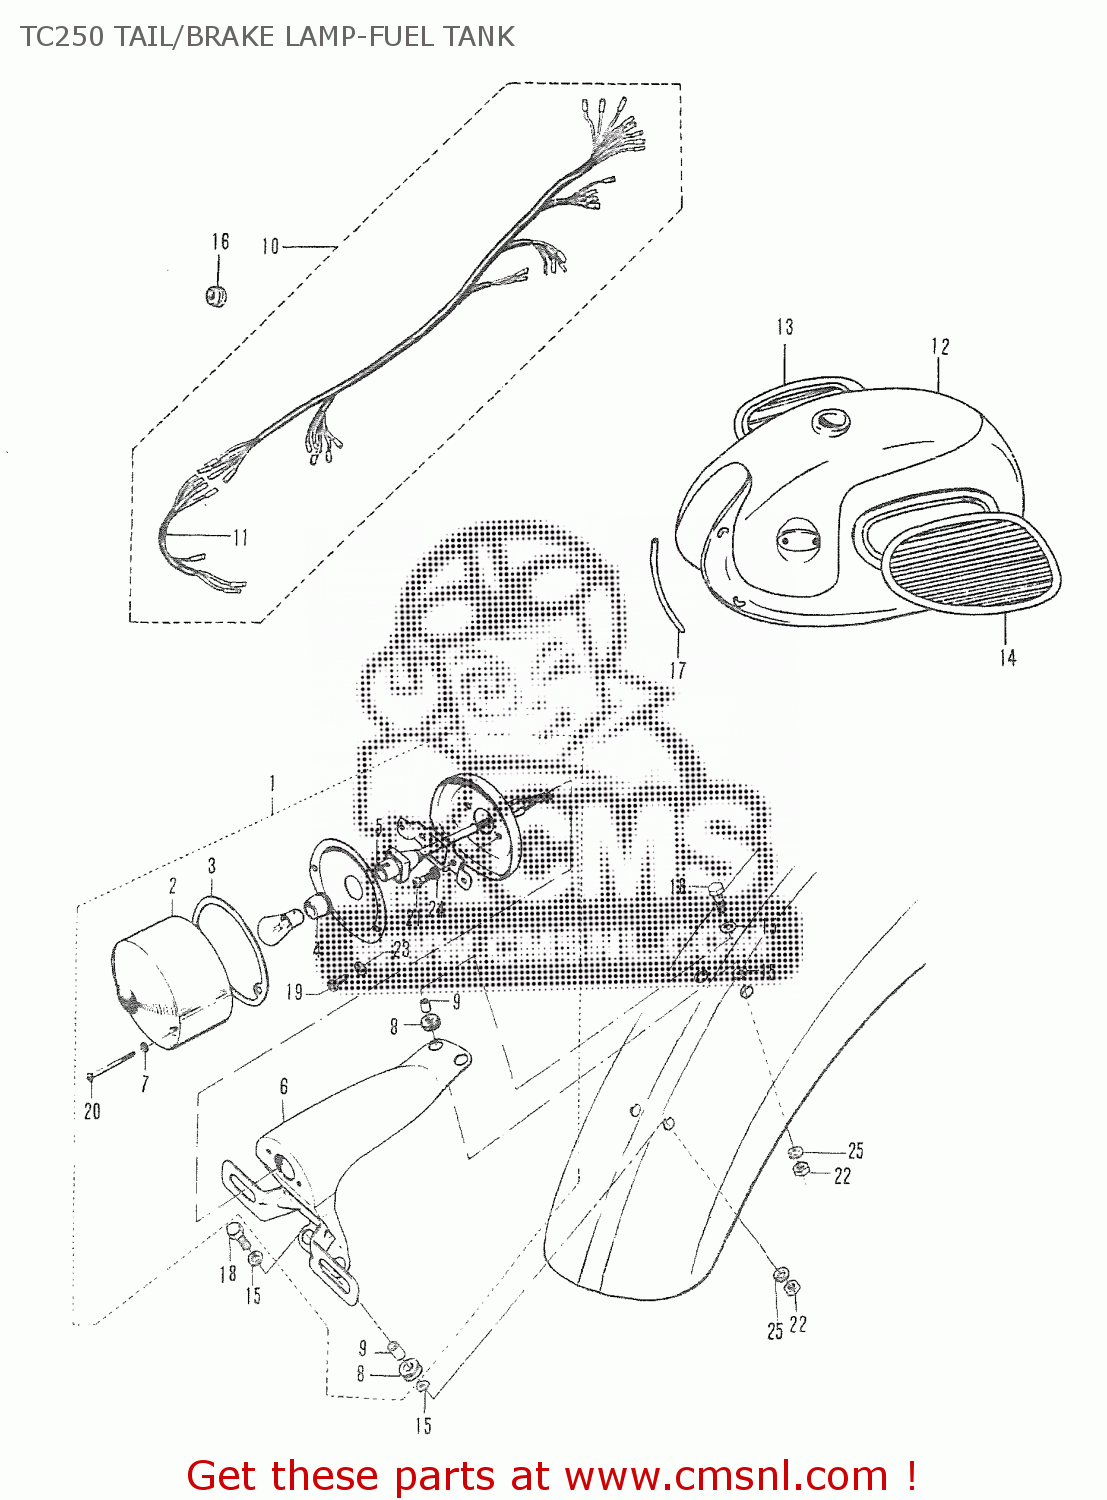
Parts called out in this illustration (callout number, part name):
1	TAIL/BRAKE LAMP ASS'Y
2	LENS,REAR COMBINATION LAMP
3	GASKET,REAR COMBINATION LAMP LENS (NAS)
4	PLATE,REAR COMBINATION LAMP
5	SOCKET & CORD ASSEMBLY
6	TAIL/BRAKE LAMP BRACKET
7	WASHER,REAR COMBINATION LAMP
8	CUSHION
9	SPACER,REAR COMBINATION LAMP
10	MAIN WIRING HARNESS ASS'Y
11	TAIL/BRAKE LAMP WIRING HARNESS
12	FUEL TANK
13	RIGHT KNEE GRIP
14	LEFT KNEE GRIP
15	WASHER
16	GROMMET
17	HOSE
18	HEXAGON BOLT
19	CROSS HEAD SCREW
20	CROSS HEAD SCREW
21	CROSS HEAD SCREW
22	HEXAGON NUT
23	LOCK WASHER
24	LOCK WASHER
25	LOCK WASHER
